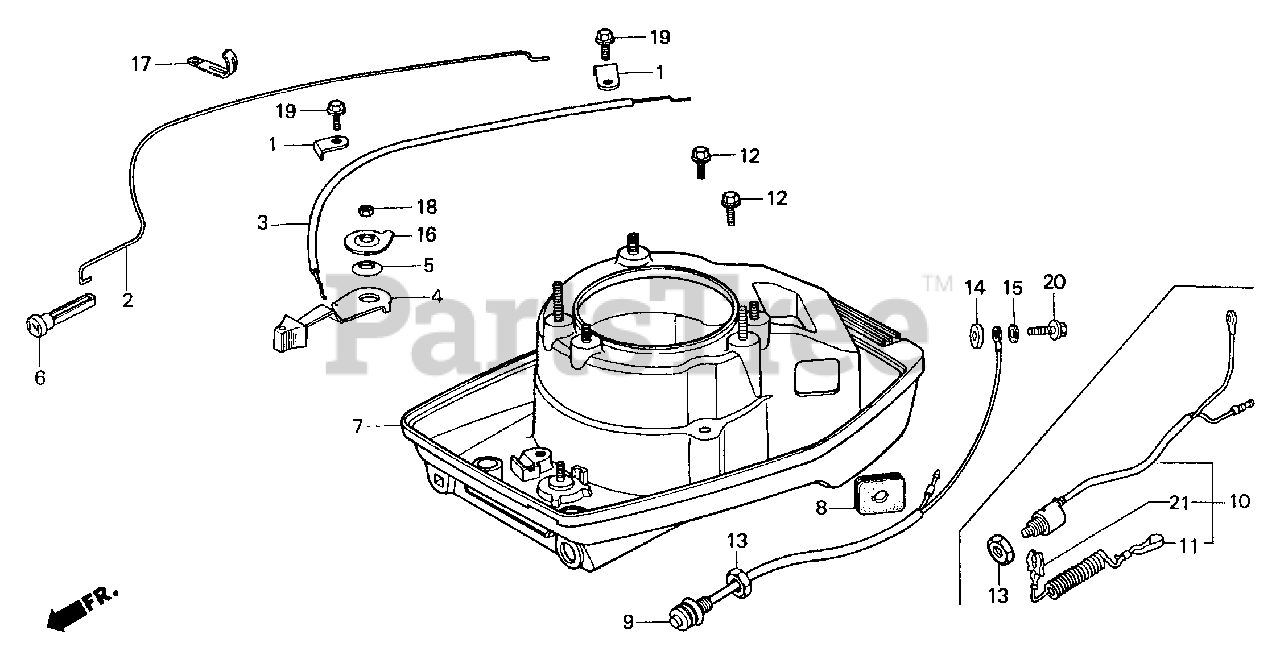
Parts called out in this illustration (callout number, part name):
1	HOLDER, CABLE
2	ROD, CHOKE
3	CABLE, THROTTLE
4	LEVER, THROTTLE
5	SPRING, LEVER
6	KNOB, CHOKE
7	COVER, FAN
8	GROMMET, FAN COVER
9	SWITCH ASSY., KILL
12	BOLT, FLANGE (6X18)
13	NUT, HEX. (16MM)
14	WASHER, FAN COVER
15	GASKET, FIBER (6MM)
16	WASHER, CONTROL LEVER
17	CLIP, WIRE
18	NUT, CAP (6MM)
19	BOLT, FLANGE (6X12)
20	BOLT, FLANGE (6X18)
